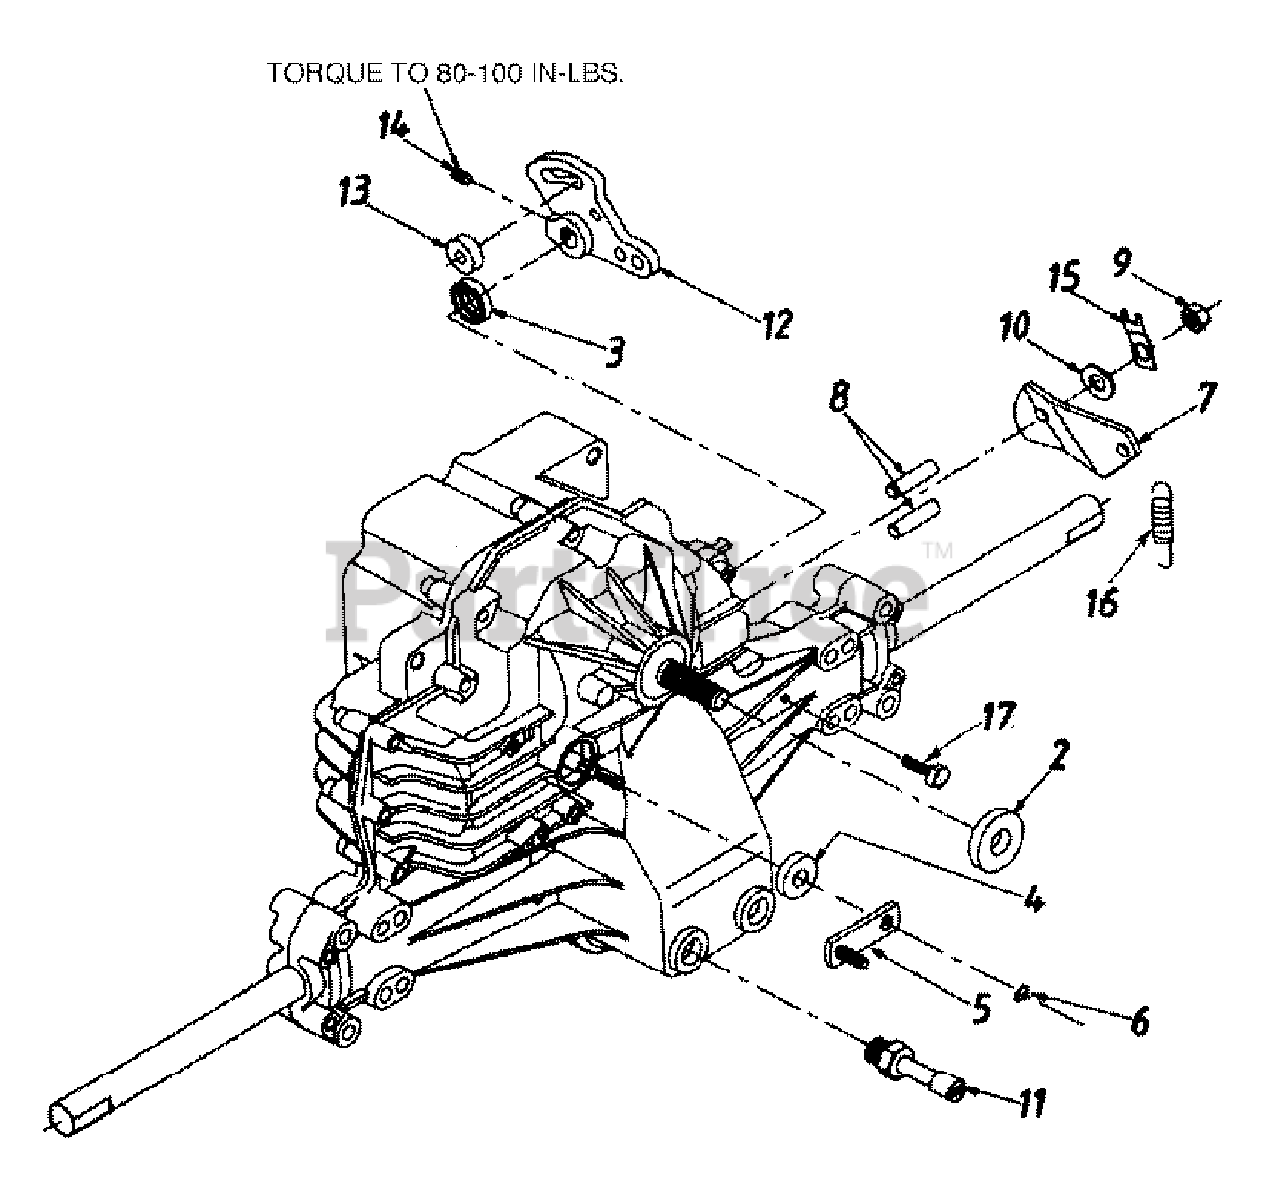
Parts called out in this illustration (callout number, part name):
4	Seal-Lip 10X25X7
6	Ring-Retaining
7	Arm-Actuating
8	Pin-Actuating
9	Nut-Hex Lock 5/16-24 UNJC
10	Washer 7/16" x 7/8" x .06"
11	Breather Ass'y.
13	Puck-Dampener
15	Strap, Locking
16	Spring, Extension
17	Self Tapp. Scr. #10-.325 x .5"
